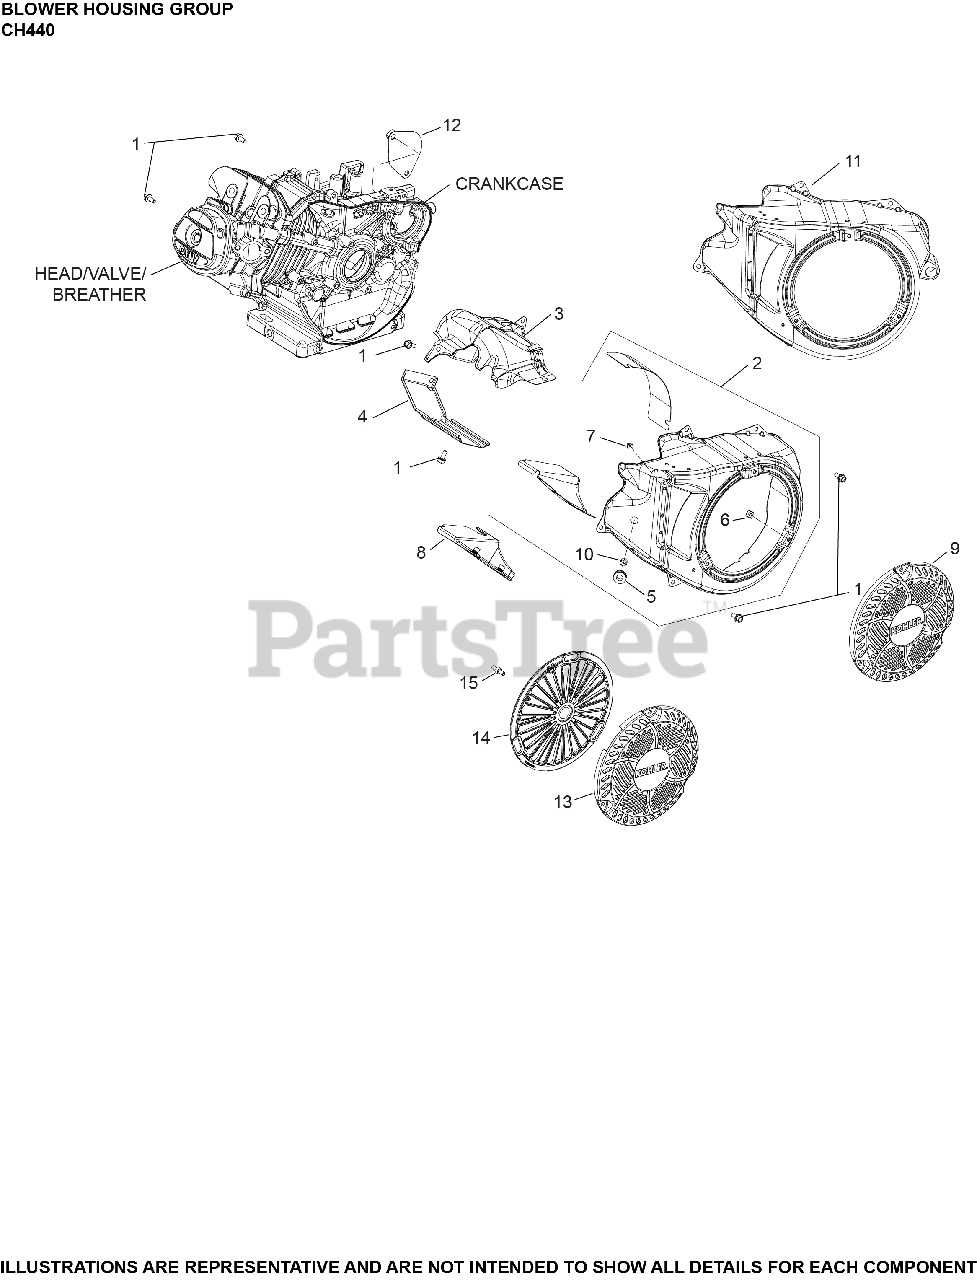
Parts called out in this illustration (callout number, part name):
2	HOUSING, BLOWER ASSEMBLY-USE 17 027 56-S
3	SHIELD, UPPER HEAT
4	SHIELD, CYLINDER HEAD
